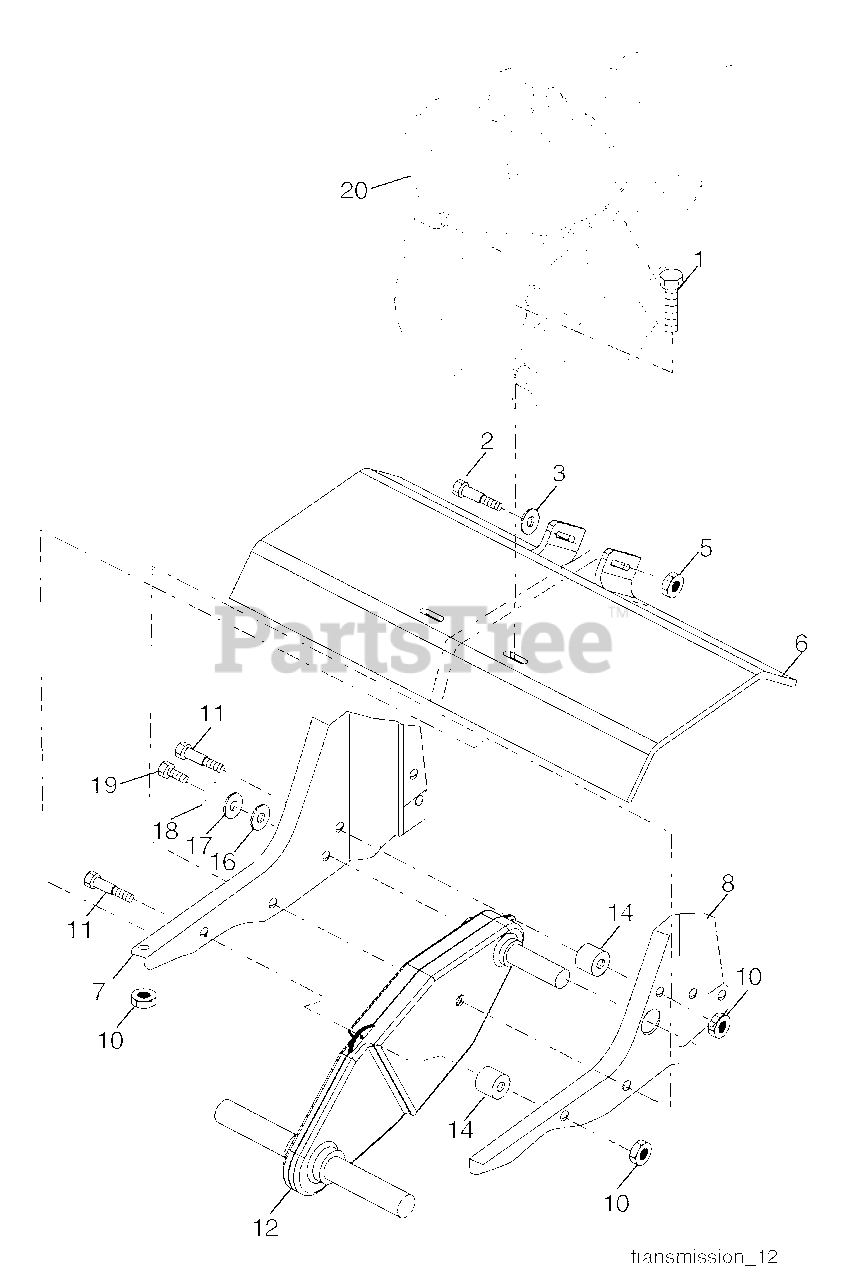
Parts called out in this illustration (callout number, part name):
1	Bolt, Hex 5/16-18 x 1-1/2 Gr. 2
2	Bolt, Hex 3/8-16 x 3-1/4
3	Washer 13/32 x 13/16 x 11
5	Locknut 3/8-16
6	Shield, Tine
7	Bracket, Engine, R.H.
8	Bracket, Engine, L.H.
10	Nut, Hex 5/16-18
11	Bolt, Hex Head 5/16-18 x 2.5
12	Transmission
14	Spacer, Split
16	Washer 9/32 x 7/8 x 12 Ga.
17	Washer 9/32 x 1-1/4 x 16 Ga.
18	Washer, Lock 1/4
19	Bolt, Hex 1/4-28 x 3/4 Gr. 5
